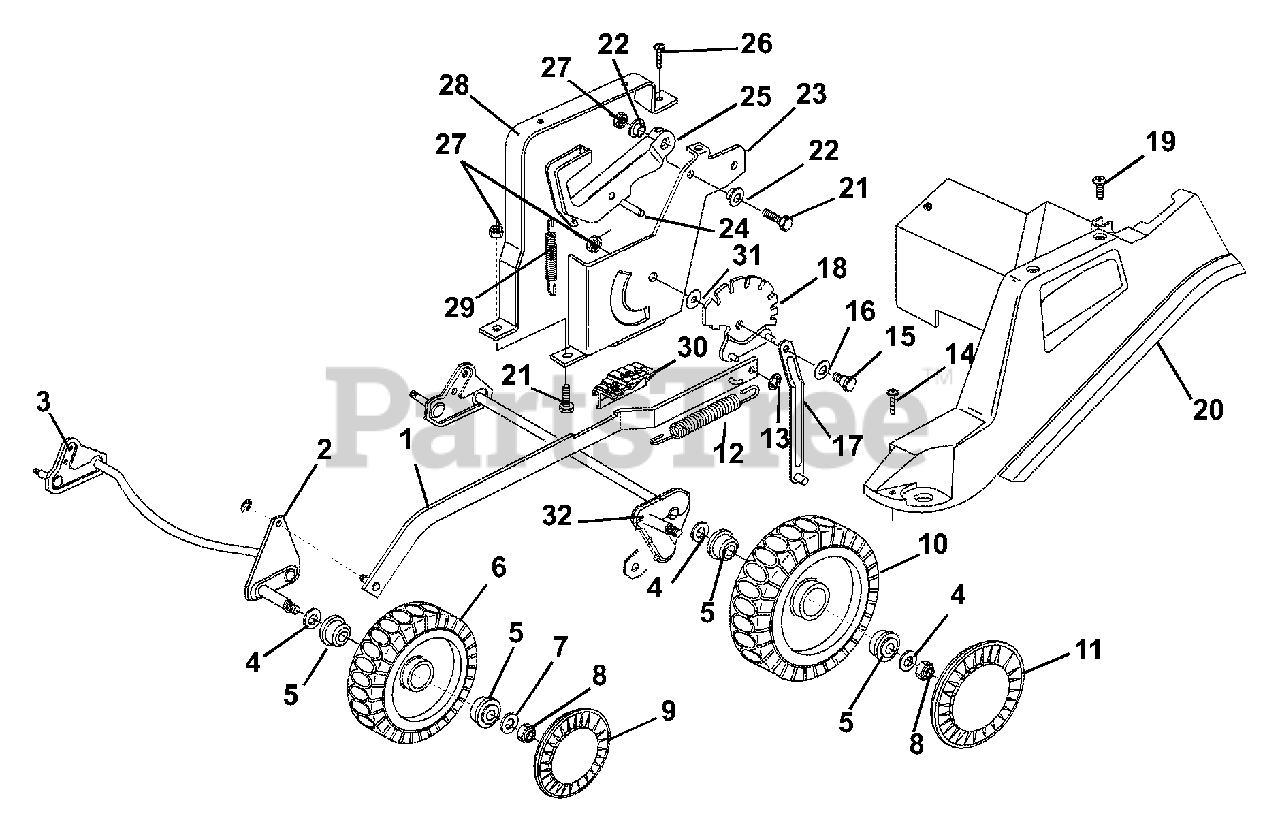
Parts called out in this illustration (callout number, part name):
1	ROD, HEIGHT ADJUSTMENT CONTROL
2	RING, SNAP
3	AXLE, FRONT WHEEL
4	WASHER, ELASTIC M12
5	BEARING
6	WHEEL, FRONT KNOBBLY 170
7	WASHER M8 8.4X16X1.6
9	HUB, CAP FRONT GREY
10	WHEEL, REAR KNOBBLY 210
11	HUB, CAP REAR GREY
13	RING, ELASTIC
14	SCREW 5.5X16
15	PIN, FULCRUM
17	ROD, REAR WHEEL AXLE
18	SECTOR, HEIGHT ADJUSTMENT
19	SCREW 5.5X13
20	DECK, ADJUSTMENT
21	SCREW M8X25
22	BUSHING
23	SUPPORT, HEIGHT ADJUSTMENT
24	PIN 6X28
26	SCREW 5.5X16
27	NUT M8 FLANGE
28	SUPPORT, HANDLE
30	PLATE, CUTTING POSITION
32	AXLE, REAR WHEEL (PUSH)
